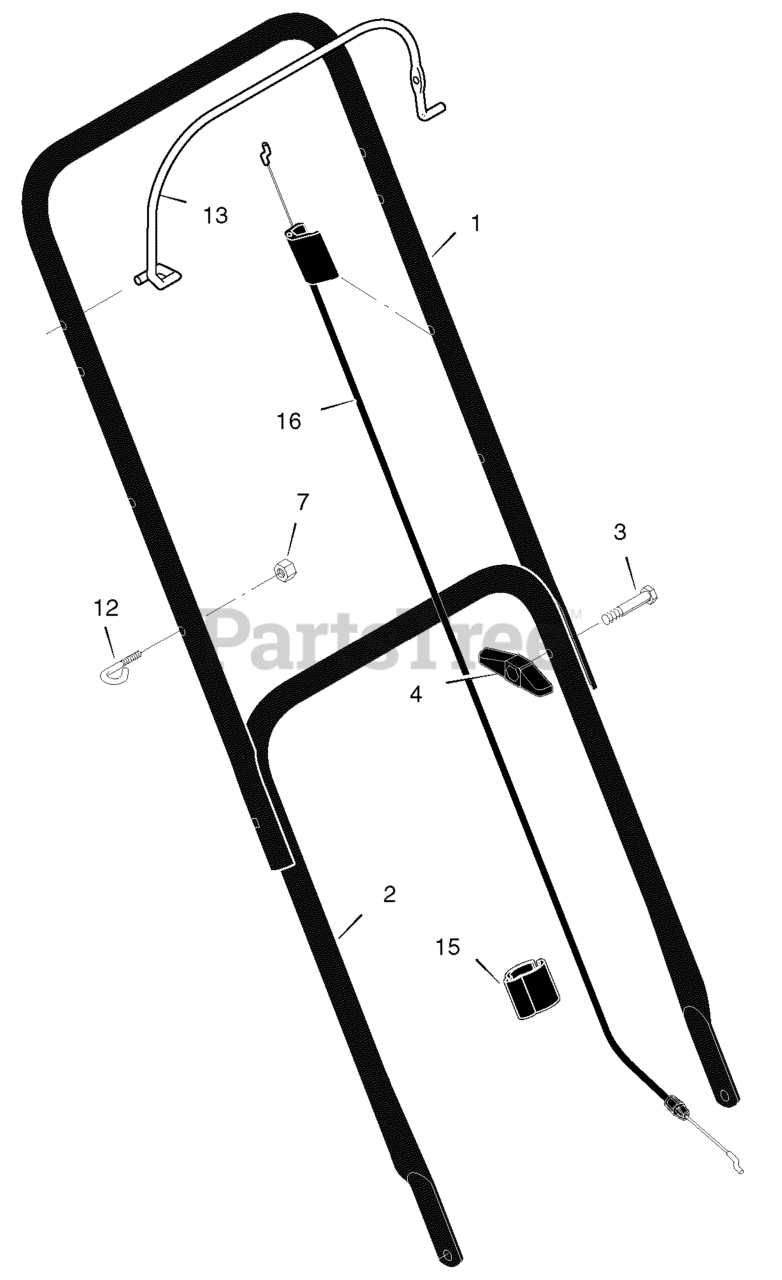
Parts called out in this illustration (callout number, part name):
1	Handle, Upper (Black)
2	Handle, Lower (Black)
4	Knob, Plastic
7	Locknut
12	Guide, Rope
13	Engine Stop Lever
15	Fastener, Cable
16	Engine Stop Cable
